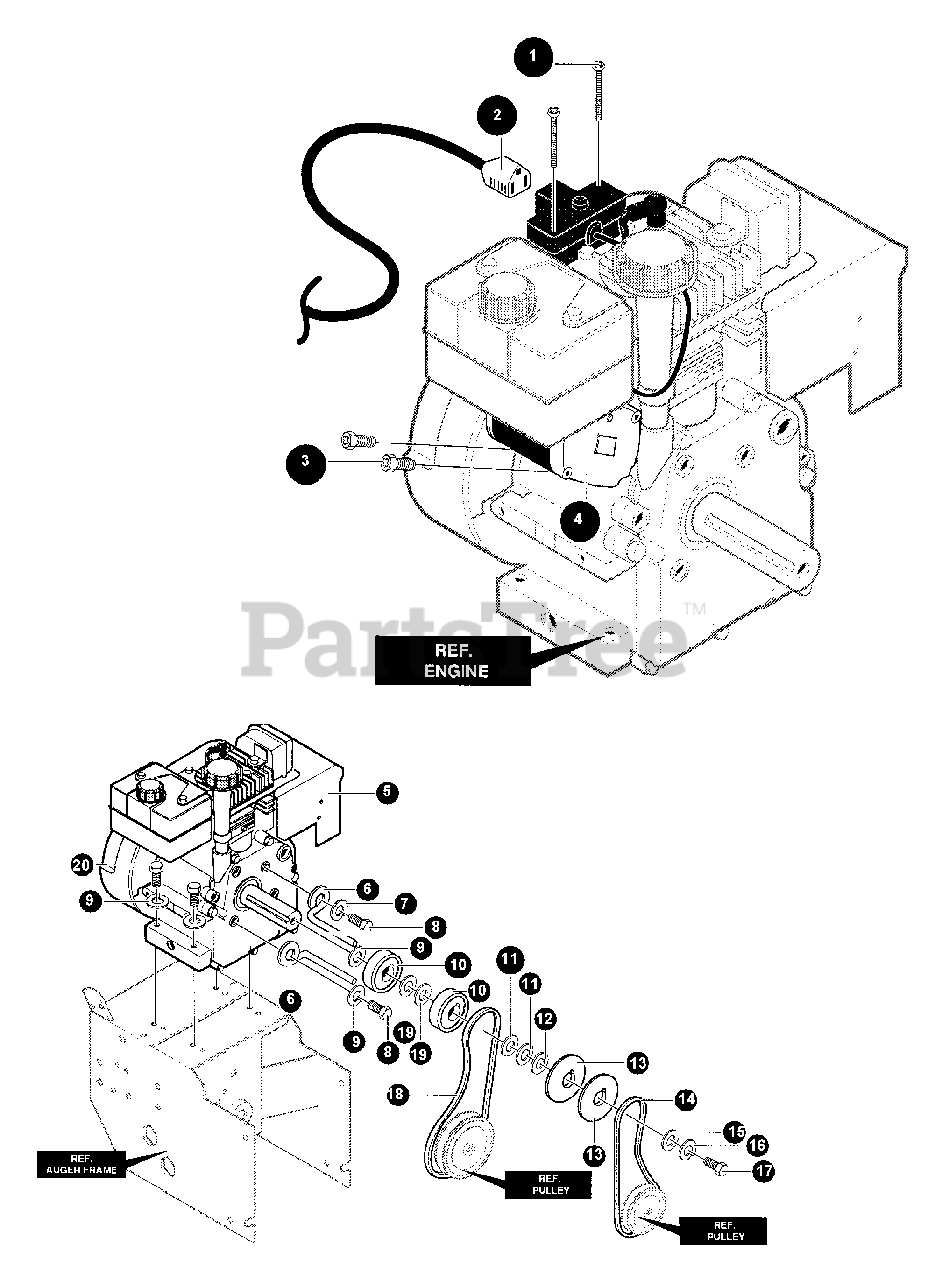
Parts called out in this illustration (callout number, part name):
1	SCREW - 6-32×2.50" -- HEX HEAD CAP
2	CORD, STARTER MOTOR
3	SCREW - 1/4-20×0.50"
4	MOTOR, STARTER TEC
6	GUIDE, ROD BELT - RIGHT
7	WASHER
8	SCREW - 5/16-24×0.625" -- HEX HEAD CAP
9	WASHER
10	PULLEY, HALF
11	WASHER, FLAT
12	SPACER
13	PULLEY, ENGINE
14	BELT, AUGER 4L 36.8
15	WASHER
16	WASHER. REGSPTLK 0.393×0.68×0.10
17	SCREW - 3/8-24×1.00" -- NYLON HEX HEAD
18	BELT
19	WASHER, FLAT 0.752×0.91×0.02
20	SCREW - 5/16-18
